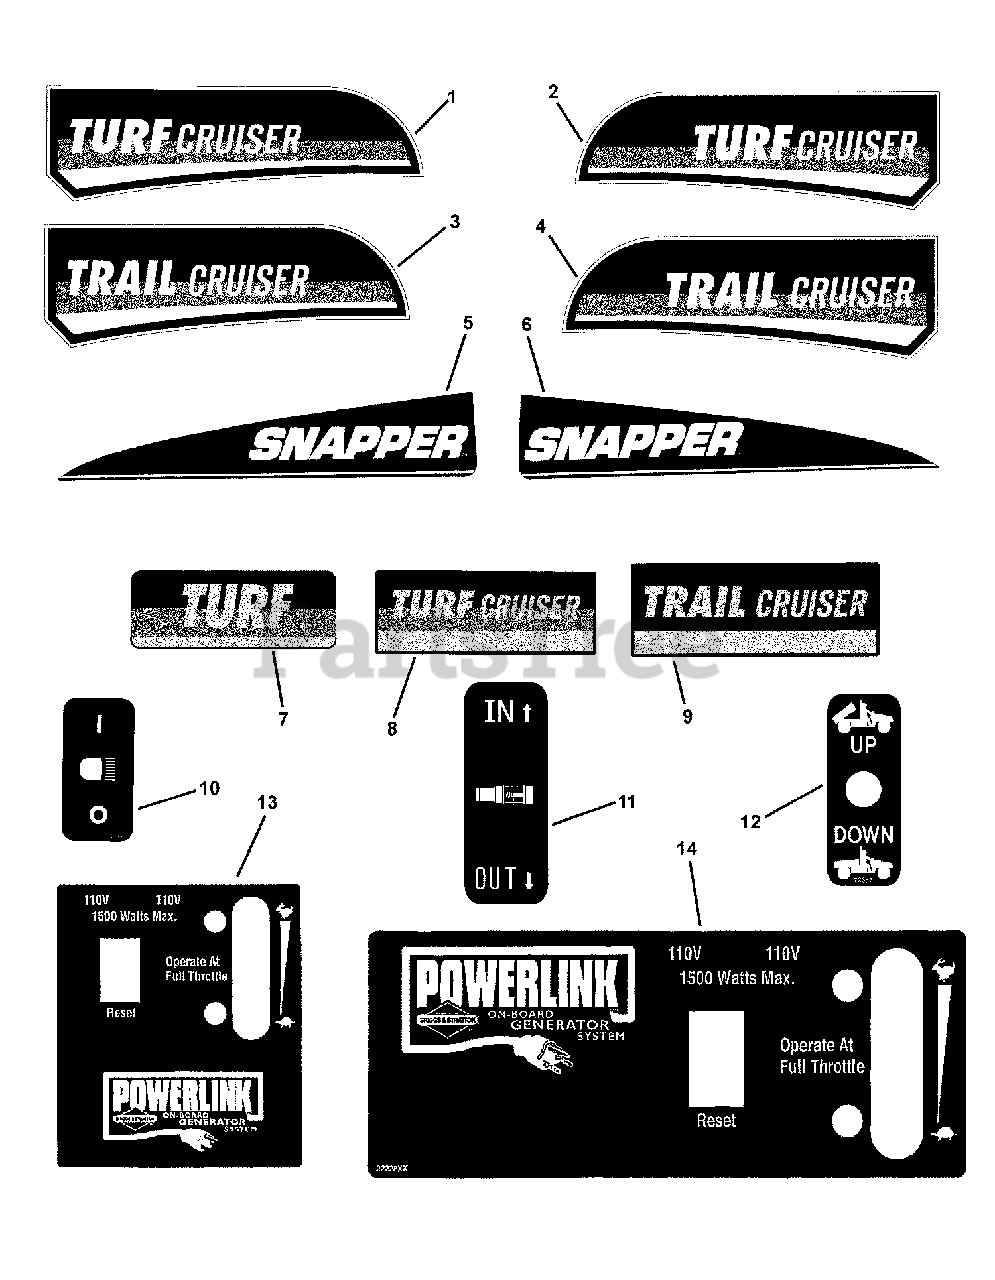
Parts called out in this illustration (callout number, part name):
9	DECAL, Grill (TrailCruiser)
10	DECAL, Light Switch
11	DECAL, Winch Switch
12	DECAL, Bed Lift
13	ROD, BRAKE CTRL, LOWER - CONZ
13	DECAL, Powerlink
14	BEARING, 1/2" FLANGED
14	DECAL, Powerlink, Generator
16	WELD, BRAKE SHAFT - RED
17	CLEVIS, 5/16-24, STEEL
18	ROD, PULLER ROD
20	GRIP, FOAM, 1/4" X 1
